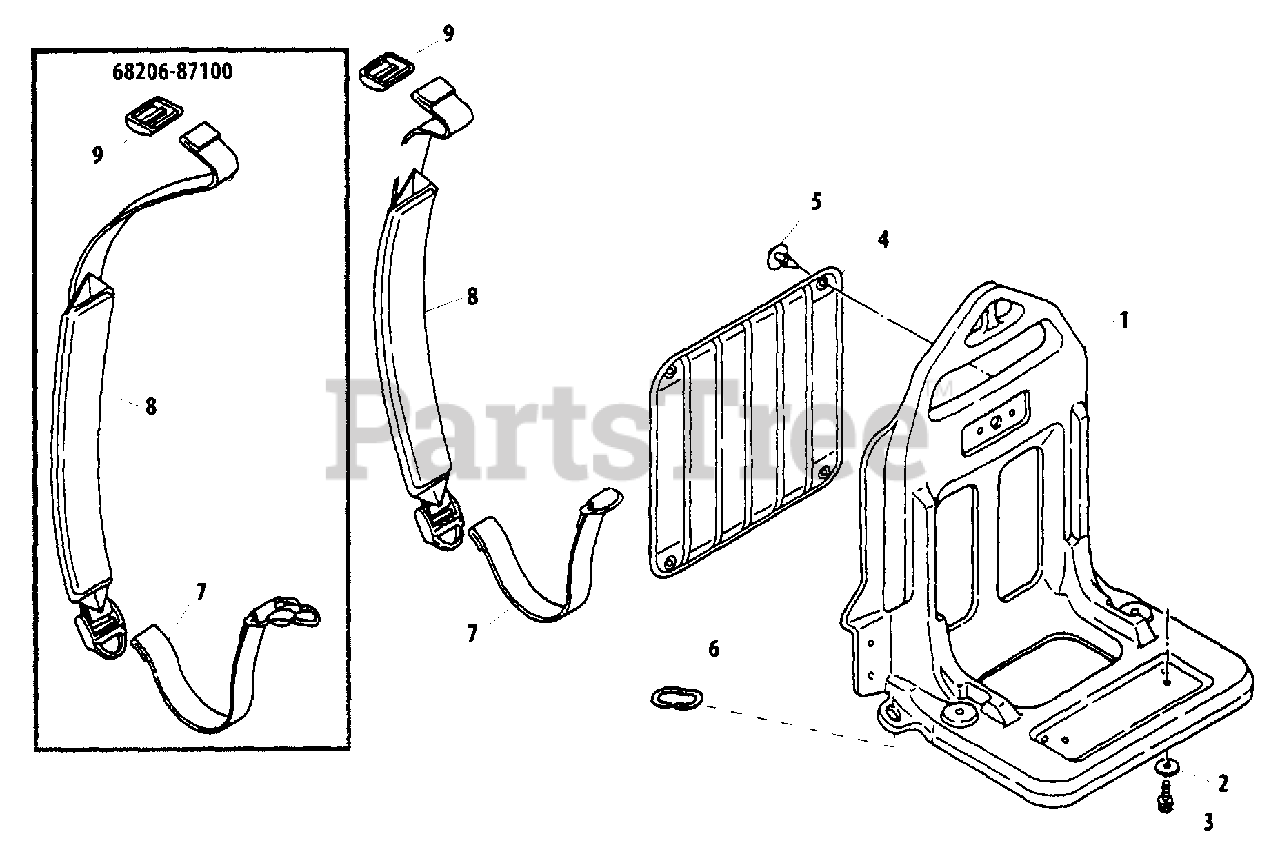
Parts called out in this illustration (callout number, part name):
1	FRAME
2	WASHER Ø15ר5.2×1.6
3	BOLT
4	PAD, BACKPACK
5	CLIP
6	RING, HARNESS
7	STRAP, HARNESS
8	HARNESS
9	BUCKLE
68206-87100	STRAP ASSY
